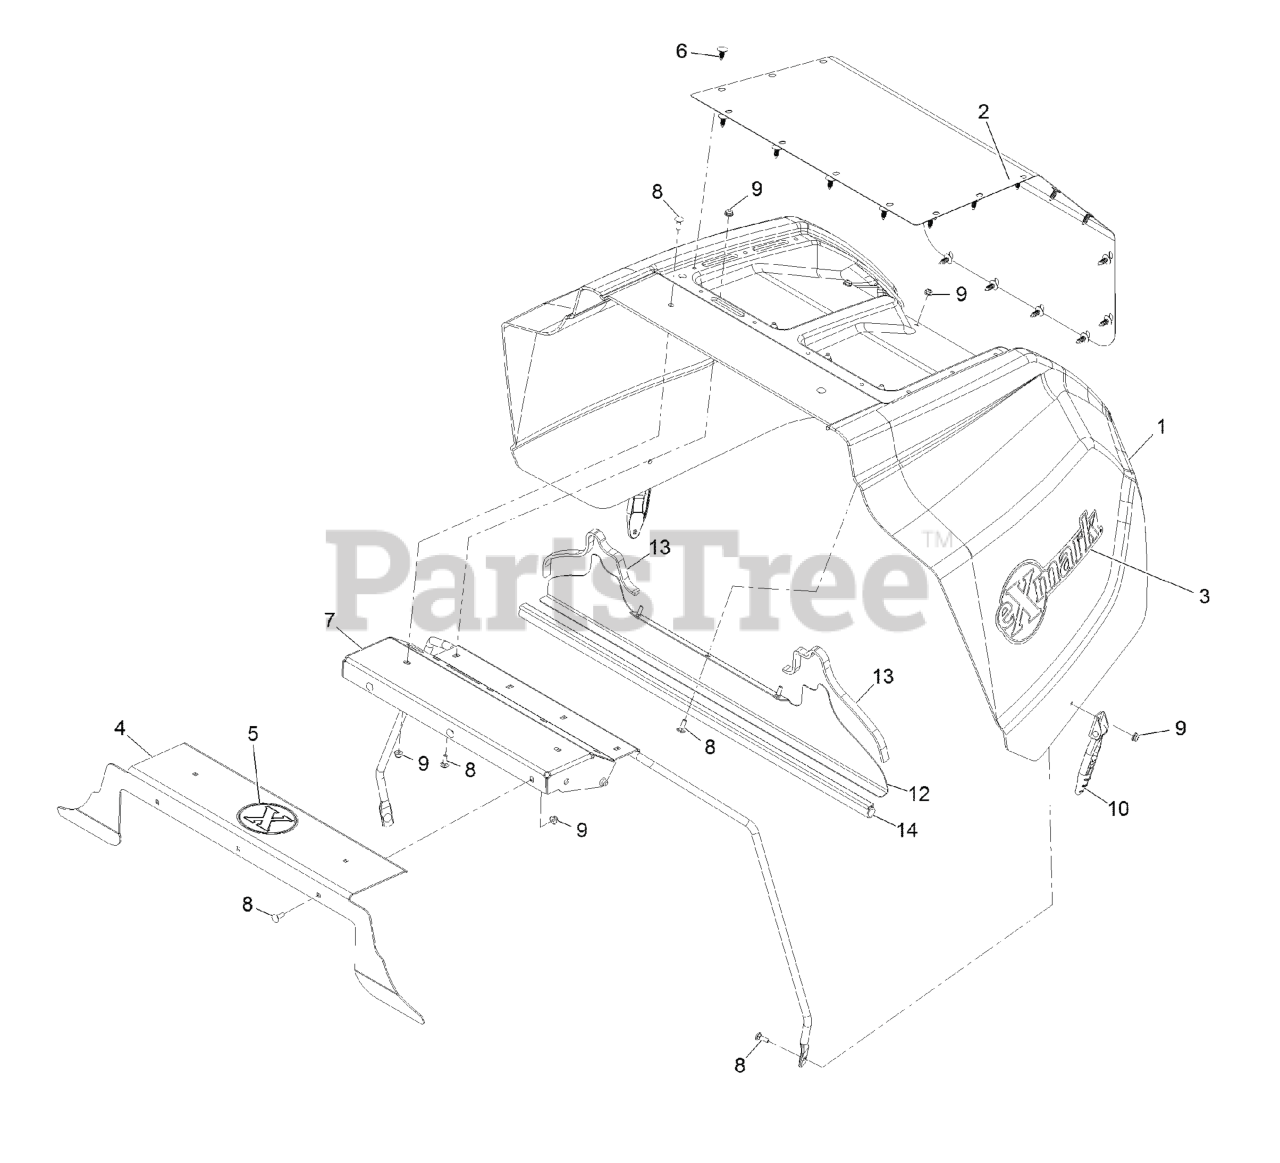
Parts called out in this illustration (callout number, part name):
2	SCREEN-INTAKE
3	DECAL-EXMARK
4	HOOD-BLOCK OFF
5	DECAL-X-LOGO
6	PLUG-PLASTIC
7	SUPPORT-HOOD
8	BOLT-CARR
10	LATCH-RUBBER
12	PLATE-SEAL
13	SEAL-FOAM
14	Seal-Bulb
